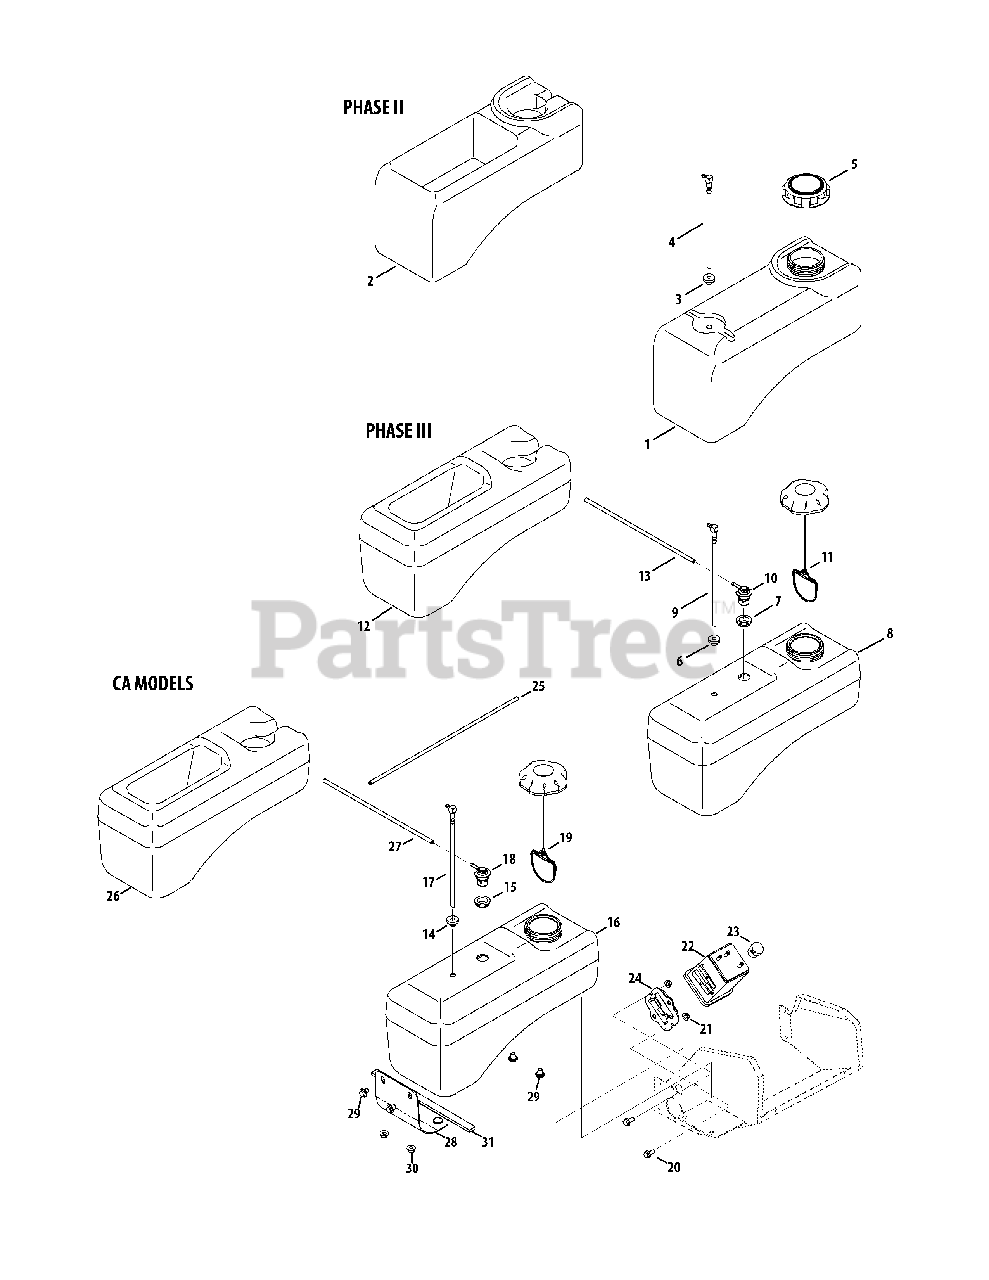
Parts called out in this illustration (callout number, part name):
1	Fuel Tank
2	Utility Bin
3	Fuel Tank Bushing
4	Fuel Pick-Up Fitting
5	Fuel Cap
6	Fuel Tank Bushing
7	Rubber Grommet
8	Fuel Tank
9	Fuel Pickup Fitting
10	Rollover Valve
11	Fuel Cap
12	Utility Bin
13	Vent Hose
14	Fuel Tank Bushing
15	Rubber Grommet
16	Fuel Tank
17	Fuel Pickup Fitting
18	Rollover Valve
19	Fuel Cap
20	Hex Flange Screw, 5/16-18
21	Flange Lock Nut, 5/16-18
22	Carbon Cannister
23	Cannister Filter Vent
24	Cannister Adapter Bracket
25	Low Perm Fuel Host 7/32 Yellow
26	Utility Bin
27	Vent Hose 3/16 Red
28	Bracket, Fuel Tank
29	Screw, Hex M10-1.5 x 12.7
30	Nut, Flange Lock 3/8-16
31	Tape, Foam .75" x .25"
